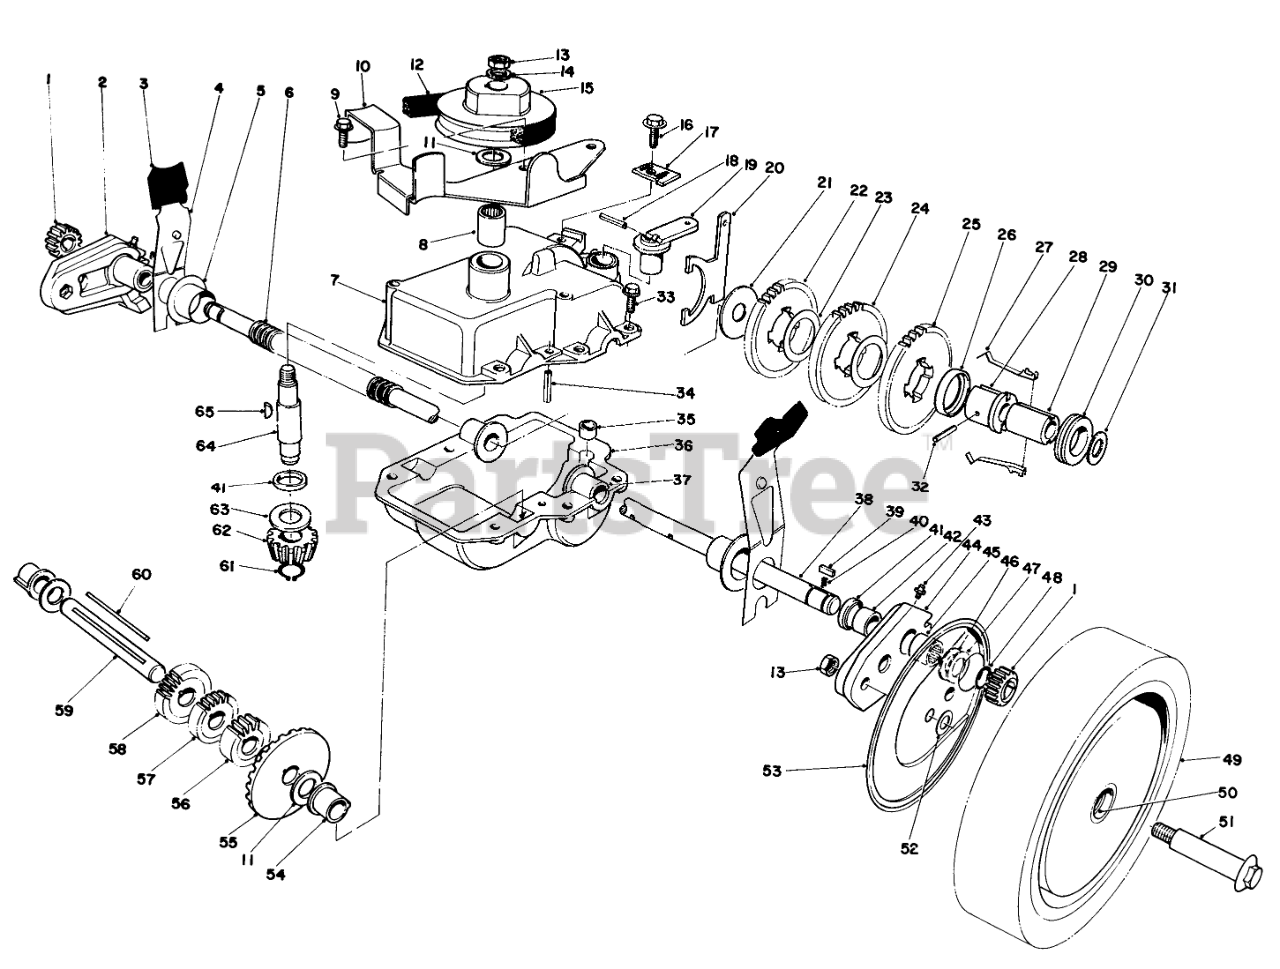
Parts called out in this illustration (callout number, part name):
1	GEAR-PINION
2	Pivot Arm Assembly-R.H.(Incl. Ref. #41-43 & 45)
3	KNOB-ARM
4	SPRING ARM ASM SP
5	CAP-END
6	CONDUIT-CONVOLUTED, SPLIT
7	Case-Upper
8	BEARING
9	SCREW
10	Bracket-Belt Guide
11	WASHER-THRUST
12	V-BELT
13	Nut
14	WASHER-FLAT
15	PULLEY
16	SCREW-HWHTF
17	Cable Clamp
18	PIN-COIL
19	LEVER-SHIFT
20	Shift Yoke
21	WASHER
22	GEAR-38T
23	WASHER
24	GEAR-42T
26	KEY RETAINER
27	Key
28	Body-Sleeve
29	SLEEVE
30	COLLAR-SHIFT
31	WASHER-PLAIN
32	PIN-SPRING
33	SCREW-HWH, THREAD ROLL
34	ROLL PIN 3/16 X 1 IN
35	BUSHING-YOKE
36	LOWER GEAR CASE CAST
37	Bushing-Output Shaft
38	Output Shaft
39	KEY RECTANGULAR
40	SPRING-COMPRESSION
42	BUSHING
43	FITTING-GREASE
44	Pivot Arm Assembly-L.H.(Incl. Ref. #41-43 8 45)
45	BEARING-ROLLER
46	Washer
47	THRUST WASHER
48	RING-RETAINING
49	Wheel, Tire & Gear Assembly (Incl. Ref. #50)
50	BUSHING
51	BOLT-WHEEL
52	WASHER
53	WHEEL COVER
54	BUSHING
55	BEVEL GEAR
56	GEAR-12T
57	GEAR-14T
58	GEAR-18T
59	INTERMEDIATE SHAFT
60	Key Square
61	RING-RETAINING
62	PINION-BEVEL
63	WASHER-THRUST
64	INPUT SHAFT
65	KEY-WOODRUFF
